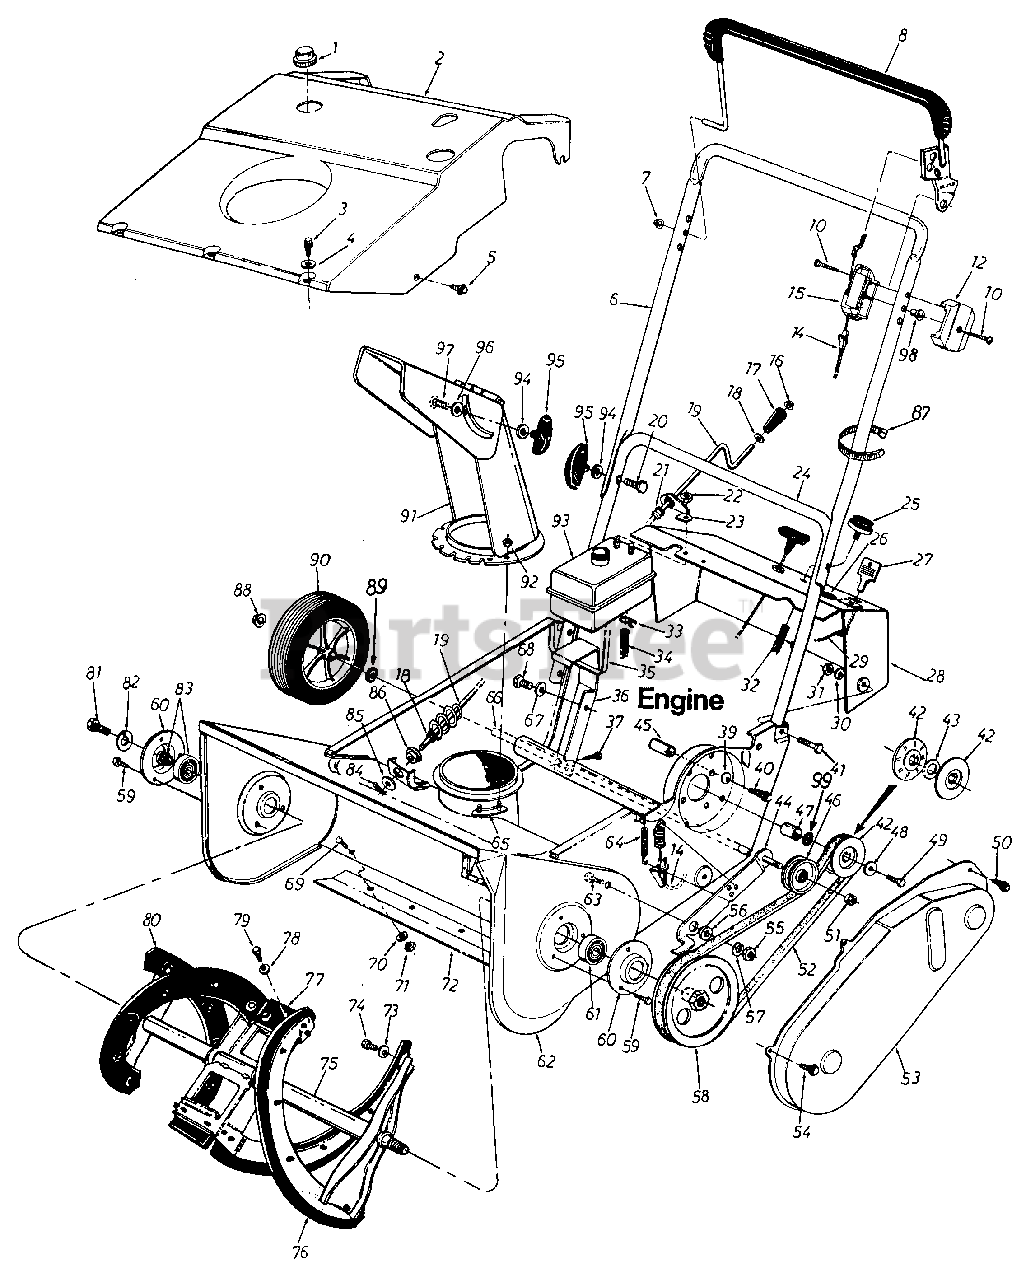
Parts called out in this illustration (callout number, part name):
1	CAP-GAS
3	SCREW-HEX B-TAP #10 X .38
4	WASHER-SPRING
5	SCREW-HEX L-WASH HD
6	HANDLE-UPPER
7	NUT-SPEED
8	HANDLE ASSY-CONTROL-LH
10	SCREW-TRUSS MACH
12	PANEL HALF-CONTROL
14	CABLE-CLUTCH
15	PANEL HALF-CONTROL
17	KNOB W/38 HOLE-BLACK
18	WASHER-FL-.385 ID X .62 OD X .063
19	CRANK ASSY-CHUTE
20	BOLT-CARRIAGE 5/16-18 X 1.75
21	GROMMET
22	NUT-HEX CENTER L-1/4-20
23	BRACKET-CHUTE CRANK
24	HANDLE-LOWER
25	PRIMER
27	KEY-STARTER-TEC
28	PANEL-DASH
29	WIRE-IGNITION
30	WASHER-LOCK-5/16
31	NUT-HEX 5/16-18
32	HOSE-PRIMER
33	CLAMP-HOSE
34	FUEL LINE-15IN
35	TIE-CABLE
36	BRACKET-ENGINE SUP
37	SCREW-HEX L-WASH HD
39	WASHER-BELL .337 X .867 X .057
40	SCREW-HEX 5/16-18 X 1.50
41	SCREW-HEX 5/16-18 X 1.50
42	PULLEY-HALF-V
43	WASHER-FL-.635 ID X .93 OD X .060
44	BRACKET ASSY-IDLER
45	SPACER
46	PULLEY-IDLER
47	SPACER
48	WASHER-BELL .337 X .867 X .057
49	SCREW-HEX 5/16-24 X .75
50	SCREW-HEX L-WASH HD
51	NUT-HEX LOCK 3/8-24
52	BELT-V
54	SCREW-HEX B-TAP 1/4 X .38
55	NUT-HEX 5/16-18
56	SPACER-SHLD
57	WASHER-LOCK-5/16
59	SCREW-HEX B-TAP 1/4 X .38
62	HOUSING ASSY-BLOWER
63	SCREW-TRUSS MACH 5/16-18 X .75
64	SPRING-EXTENSION
65	GUARD ASSY-CHUTE FLANGE
66	AXLE-WHEEL
67	LOCK WASHER 1/4 DIA
68	SCREW-HEX WASH SF TAPP
69	BOLT-CARRIAGE 1/4-20 X .62
70	WASHER-SPRING BELL
71	NUT-HEX 1/4-20
72	PLATE-SHAVE
73	WASHER-FL-.281 ID X .50 OD X .063
74	SCREW-HEX B-TAP 1/4-.62
75	AUGER ASSY 21IN
76	SPIRAL-RUBBER-LH
77	PADDLE-RUBBER
78	WASHER-FL .192 X .625 X .057
79	SCREW-TAP
80	SPIRAL-RUBBER-RH
81	SCREW-HEX WASH 1/4-20X.75
82	LOCK WASHER 1/4 DIA
83	KIT-BRG & COLLAR
84	PIN-COTTER-3/32 DIA X .75
85	WASHER-FL-.390 ID X 1.50 OD X .075
86	BUSHING-HEX
87	CLAMP-CABLE 7/8
89	WASHER-FL-.510 ID X .75 OD X .033
90	WHEEL ASSY W/TIRE-6 X 1.5
91	CHUTE ASSY
92	NUT-HEX CENTER L-1/4-20
93	TANK-FUEL
94	WASHER-BELL .337 X .867 X .057
95	KNOB-HANDLE ASSY
96	WASHER-FL
97	BOLT-CARRIAGE 5/16-18 X .62
98	PIN-CONTROL DISC
99	WASHER-FL-.635 ID X .93 OD
